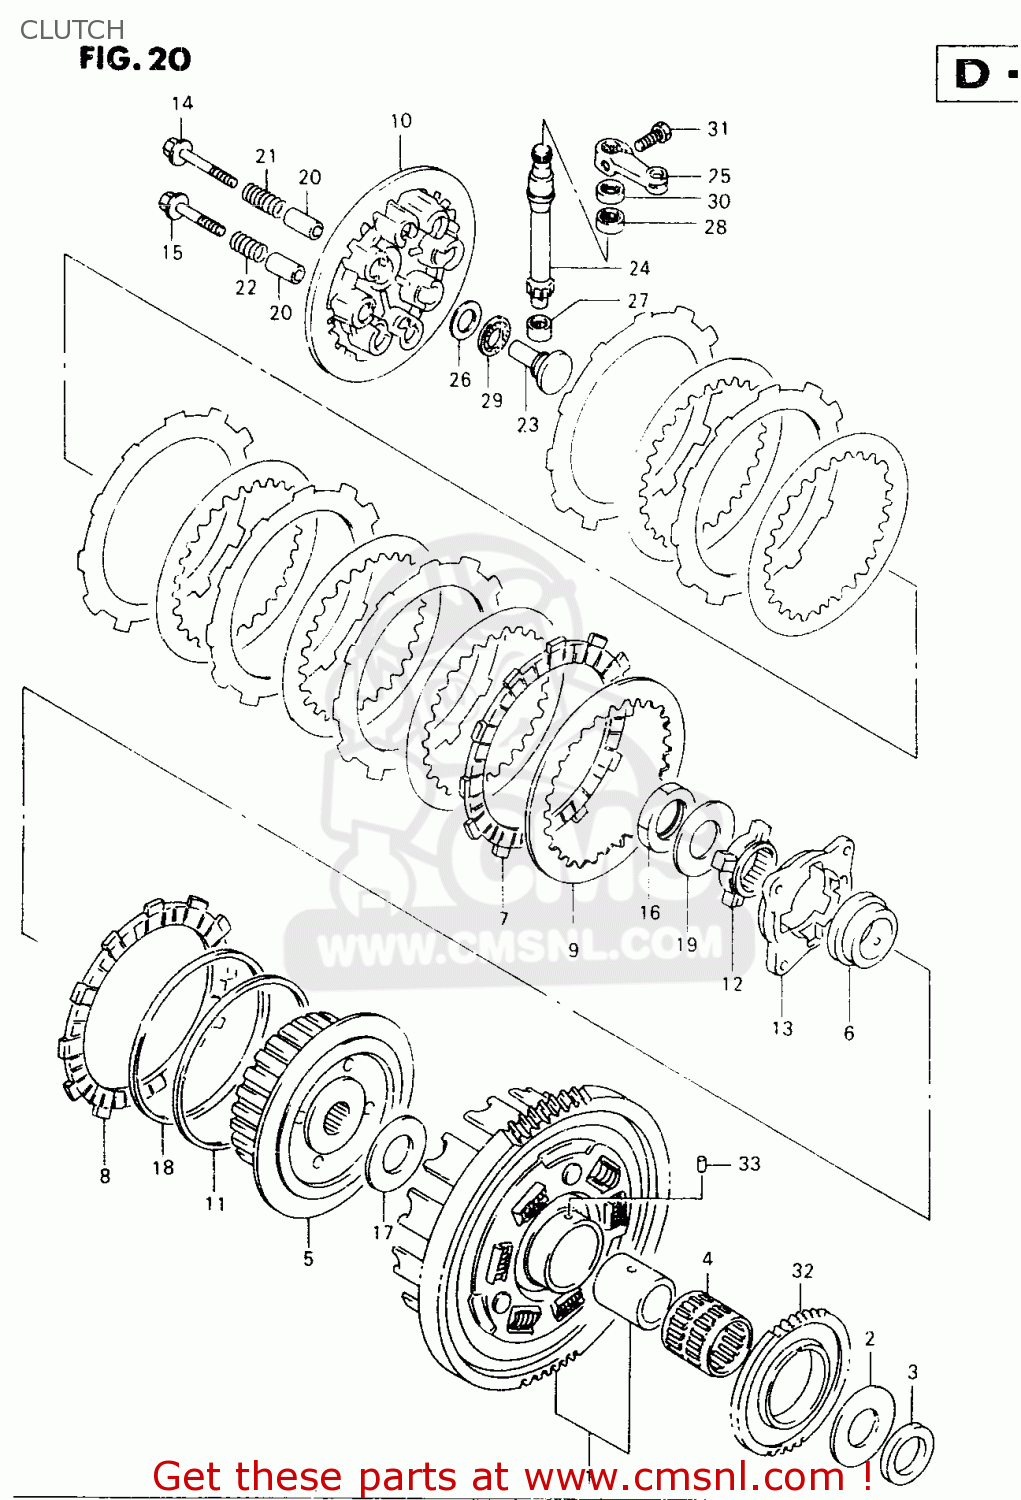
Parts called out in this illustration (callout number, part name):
1	GEAR ASSY,PRI DRIVEN
2	WASHER(25X54X2.5)
3	SPACER(25X38X6.5)
4	BEARING(35X40X35.8)
5	HUB,CLUTCH SLEEVE
6	SPACER,CLUTCH SLEEVE HUB
7	PLATE,CLUTCH DRIVE NO (NAS)
8	PLATE,CLUTCH DRIVE(T:3.5) (NAS)
9	PLATE,CLUTCH DRIVEN(T:1.6) (NAS)
10	DISC,CLUTCH PRESSURE
11	SEAT,WAVE WASHER(T:1.4)
12	CAM,CLUTCH NO.1
13	CAM,CLUTCH NO.2
14	BOLT(6X40)
15	BOLT(6X32.5)
16	NUT
17	WASHER(25X60X2.5)
18	WASHER
19	WASHER
20	SPACER(6.5X9X24.1)
21	SPRING
22	SPRING
23	RACK,CLUTCH RELEASE
24	PINION,CLUTCH RELEASE
25	ARM,CLUTCH RELEASE
26	WASHER(15.5X28X1)
27	BEARING(9X13X10)
28	BEARING(12X16X10)
29	BEARING(15X28X2)
30	SEAL,OIL(10X17X5)
31	BOLT
32	GEAR,OIL PUMP DRIVE(NT:47)
33	PIN(6X6)
